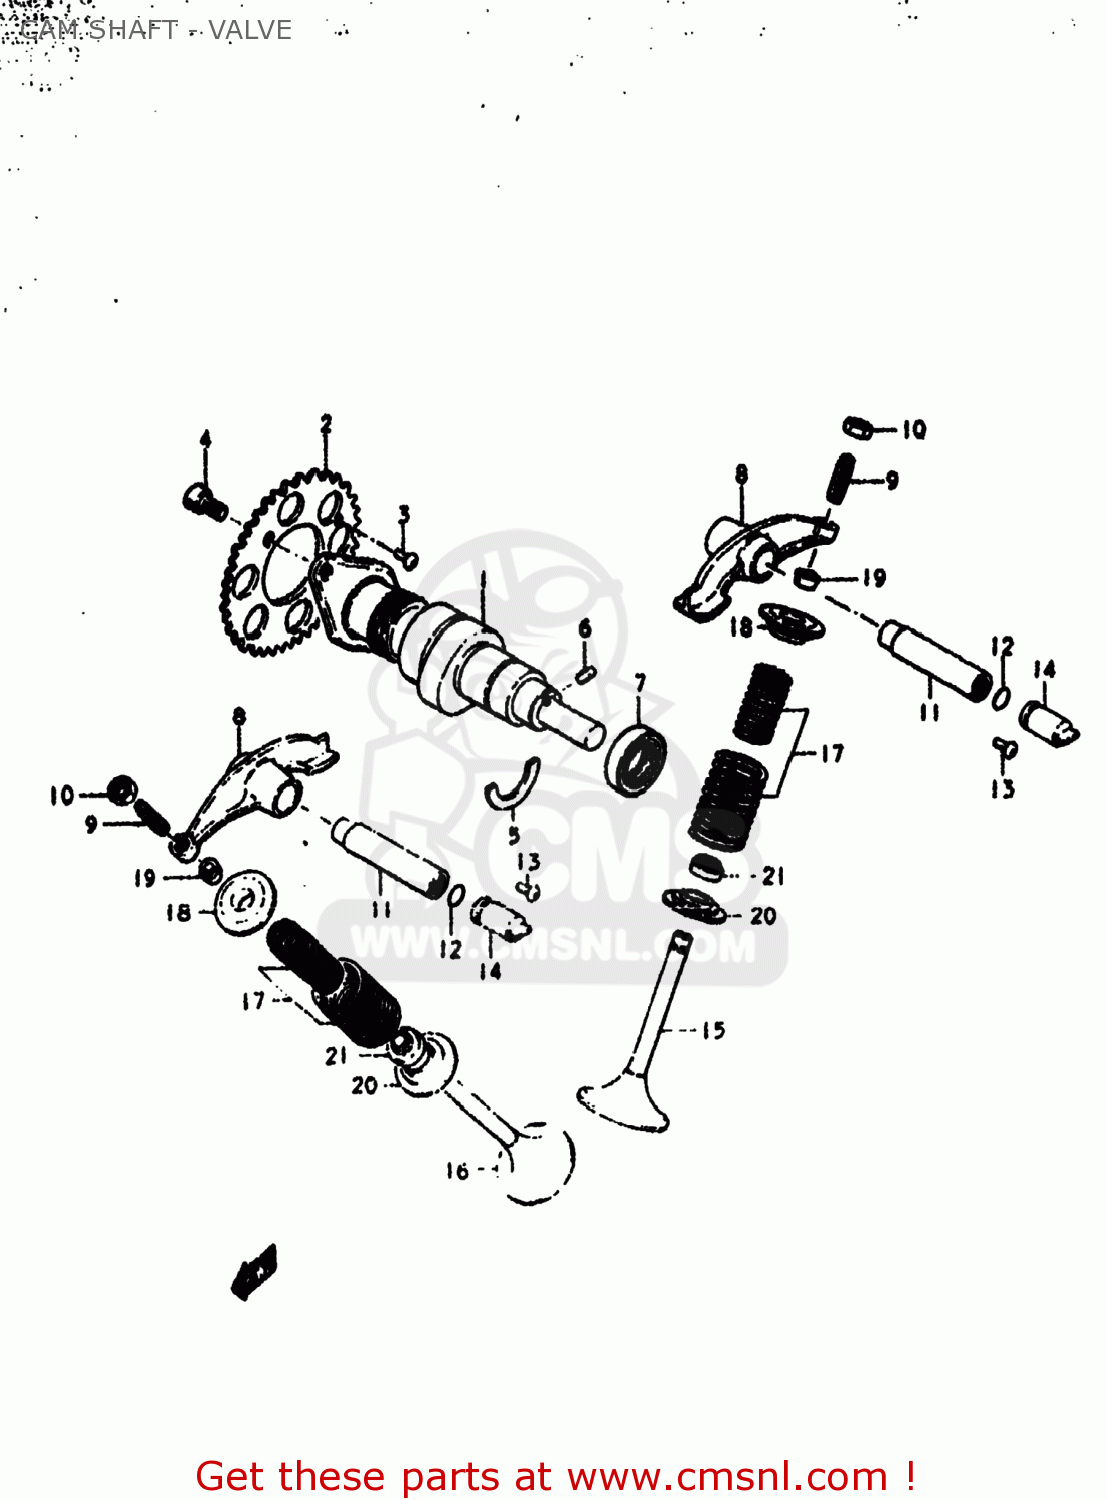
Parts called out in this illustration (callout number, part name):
1	CAMSHAFT
2	SPROCKET,CAMSHAFT
3	SCREW 5X6
4	BOLT 6X11
5	C RING
6	PIN 3X5
7	OIL SEAL (18X30X7)
8	ARM,VALVE ROCKER
9	SCREW,TAPPET ADJUSTING
10	NUT,ADJUSTING SCREW
11	SHAFT,VALVE ROCKER
12	O-RING
13	SCREW
14	CAP,ROCKER ARM SHAFT
15	VALVE,INTAKE
16	VALVE,EXHAUST
17	SHIM,TAPPET
18	RETAINER,VALVE SPRING
19	SHIM,TAPPET
20	SEAT,VALVE SPRING
21	SEAL,OIL(7X14.4X9)
